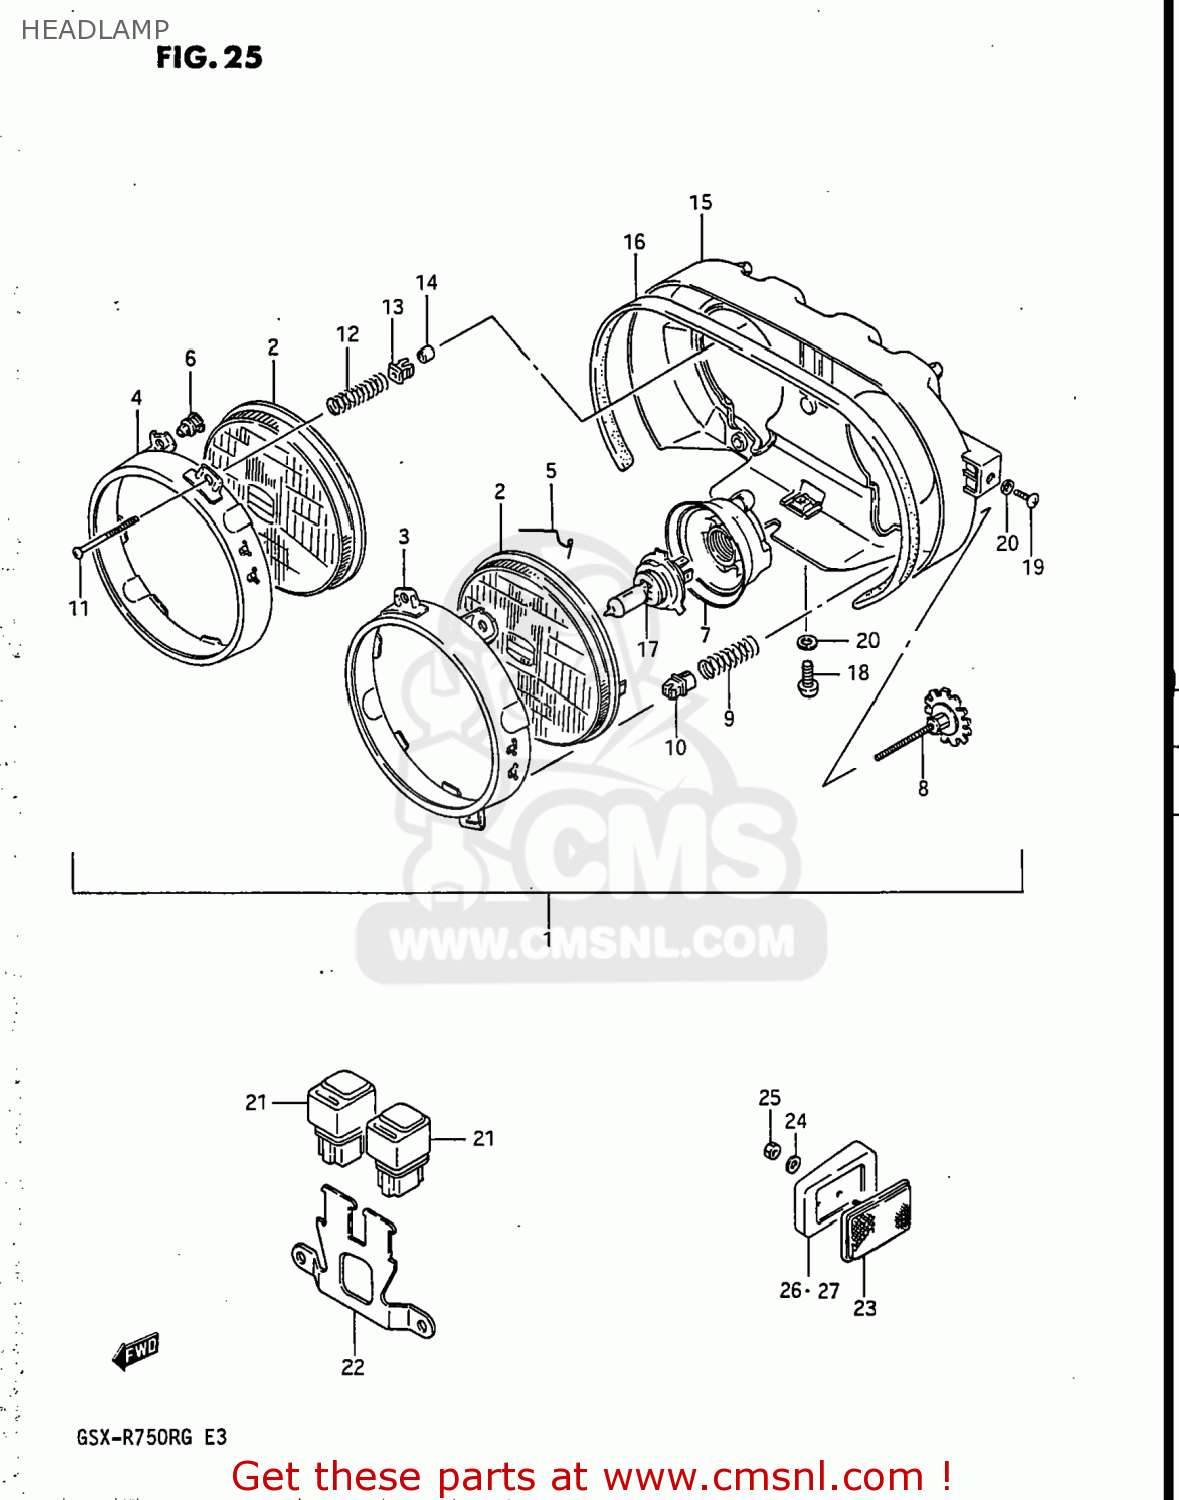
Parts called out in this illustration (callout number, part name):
1	HEADLAMP ASSY
2	LAMP UNIT
3	RING,RETAINING,LEFT
4	RING,RETAINING,RIGHT
5	SPRING
6	SCREW,SPHERICAL
7	COVER,SOCKET
8	SCREW,ADJUSTER
9	SPRING
10	NUT
11	SCREW,ADJUSTER
12	SPRING
13	NUT
14	CAP,SCREW
15	HOUSING,HEADLAMP
16	GASKET (NAS)
17	BULB(12V60/55W,H4)
18	SCREW
19	SCREW
20	WASHER,LOCK
21	RELAY, ANTINOSE DIVE FORK
22	BRACKET,HEADLAMP RELAY
23	REFLEX REFLECTOR ASSEMBLY
24	WASHER,5MM
25	NUT ,5MM
26	SPACER,FRONT SIDE,REAR,RIGHT
27	SPACER,FRONT SIDE,REAR,LEFT
